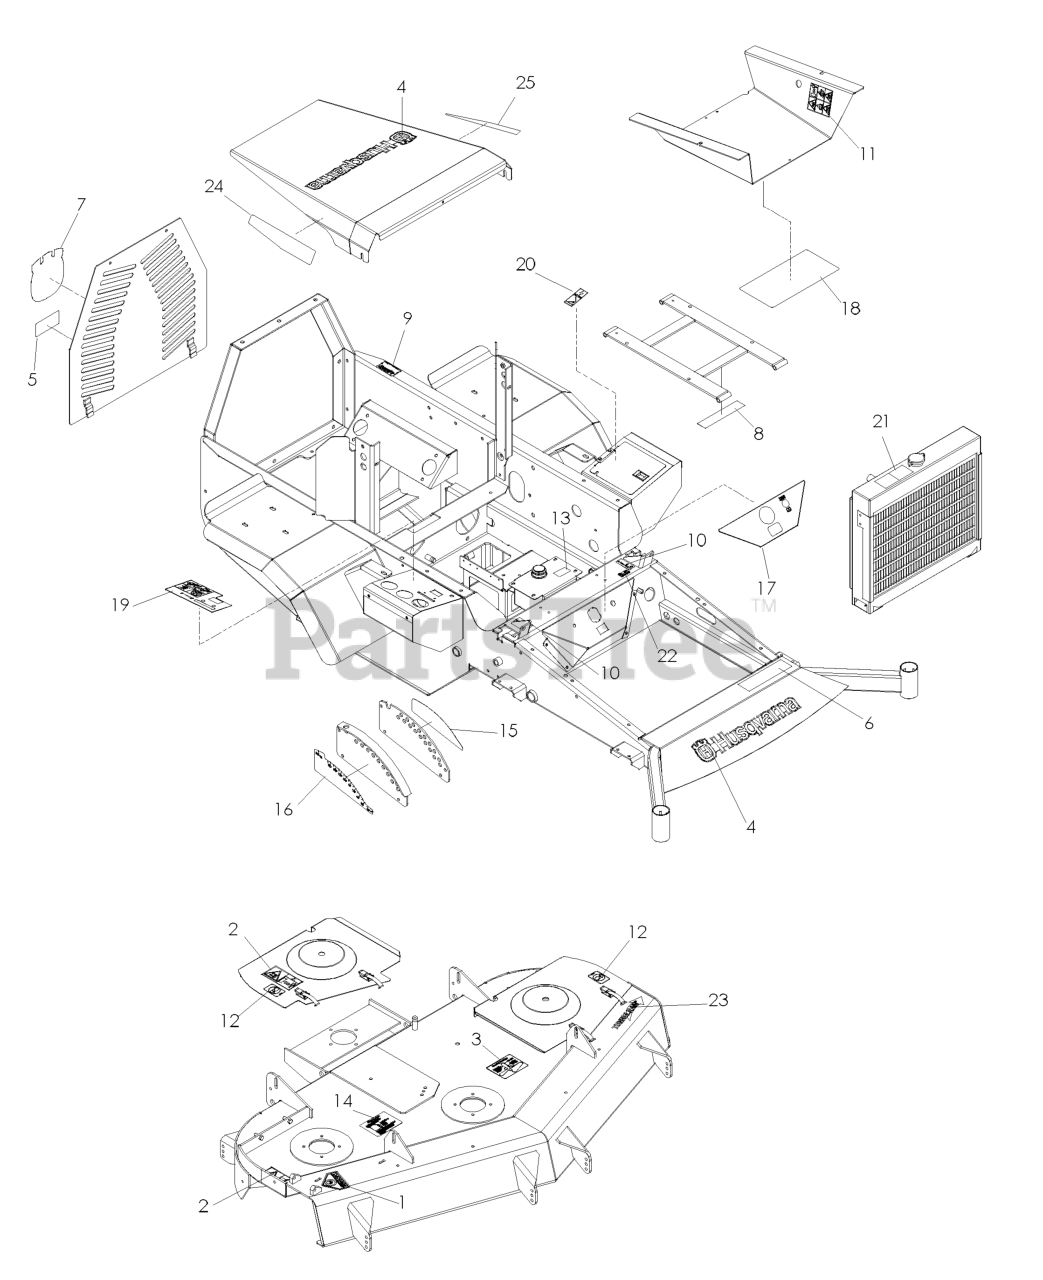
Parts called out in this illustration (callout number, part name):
1	DECAL, CPSC
2	DECAL, EURO SEVERING
3	DECAL, BELT ROUTING
4	DECAL, HUSQ 15" BLUE
5	DECAL, BELT DRIVE
6	DECAL, BZ6127
6	DECAL, BZ7234
7	DECAL, CROWN H BLUE
8	EURO DECAL-BATTERY WARNIN6
9	DECAL, PROP. 65
10	DECAL, MOTION CONTROL
11	DECAL, WARNING
12	DECAL, NO STEP
13	DECAL, OIL TANK
14	DECAL, ANTI SCALP
15	DECAL, HEIGHT
16	DECAL, HEIGHT
17	DECAL, CONSOLE
18	DECAL, SERVICE
19	DECAL, RT CONSOLE
20	DECAL, 12V D.C.
21	DECAL, HOT
22	DECAL, F.S.T.
23	DECAL, TUNNEL RAM 8"
24	DECAL, 34 TURBO RH
24	DECAL, 27HP DIESEL - RIGHT
25	DECAL, 34 TURBO LH
25	DECAL, 27HP DIESEL LEFT
